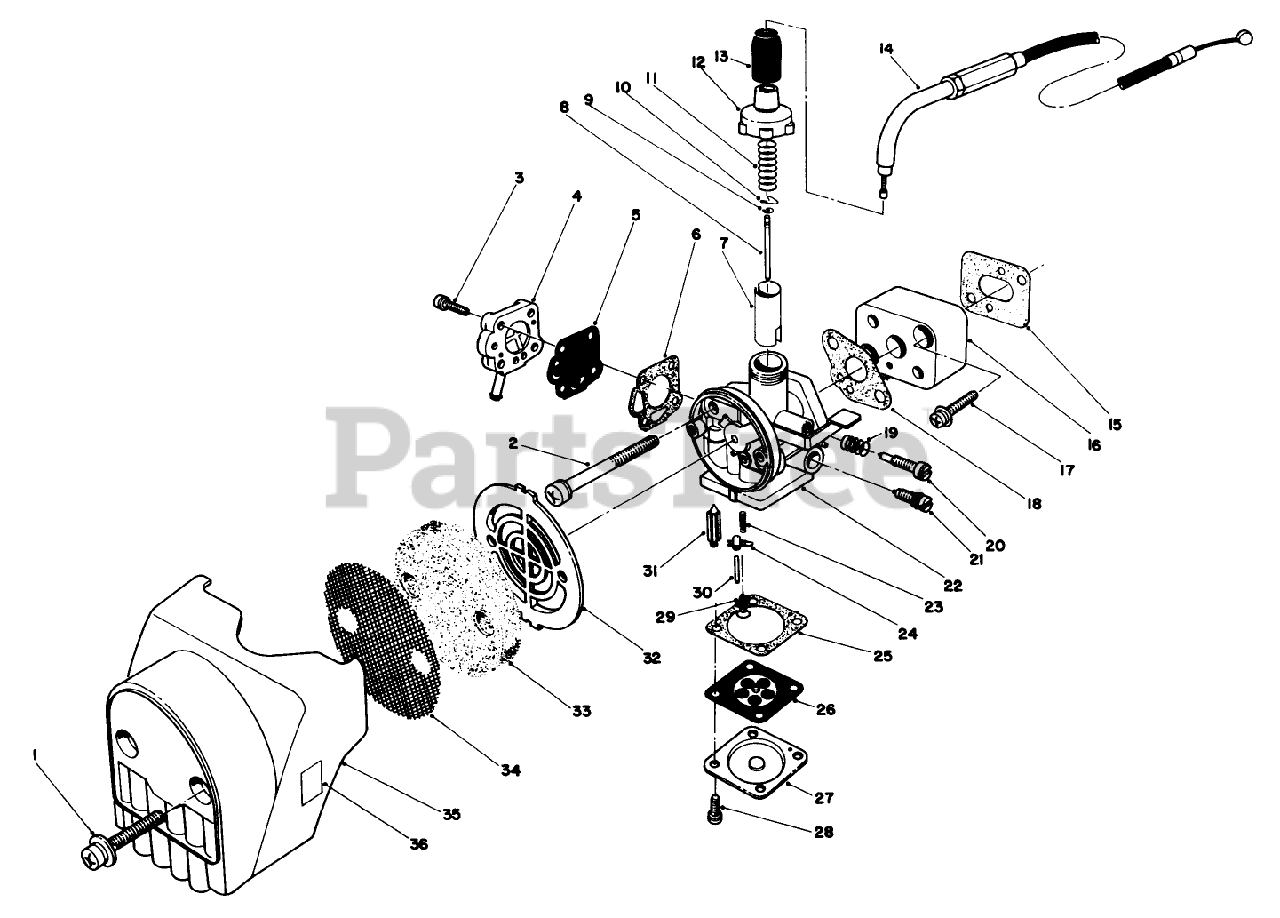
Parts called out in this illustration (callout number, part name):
2	SCREW W/ WASHER
13	AIR SEAL
15	GASKET, INSULATOR
21	MAIN NEEDLE
22	CARBURETOR (D)
24	FLOAT ARM
25	DIAPHRAGM GASKET
27	DIAPHRAGM COVER
29	FLOAT SCREW
33	ELEMENT
35	COVER, CLEANER
36	CHOKE LABEL
